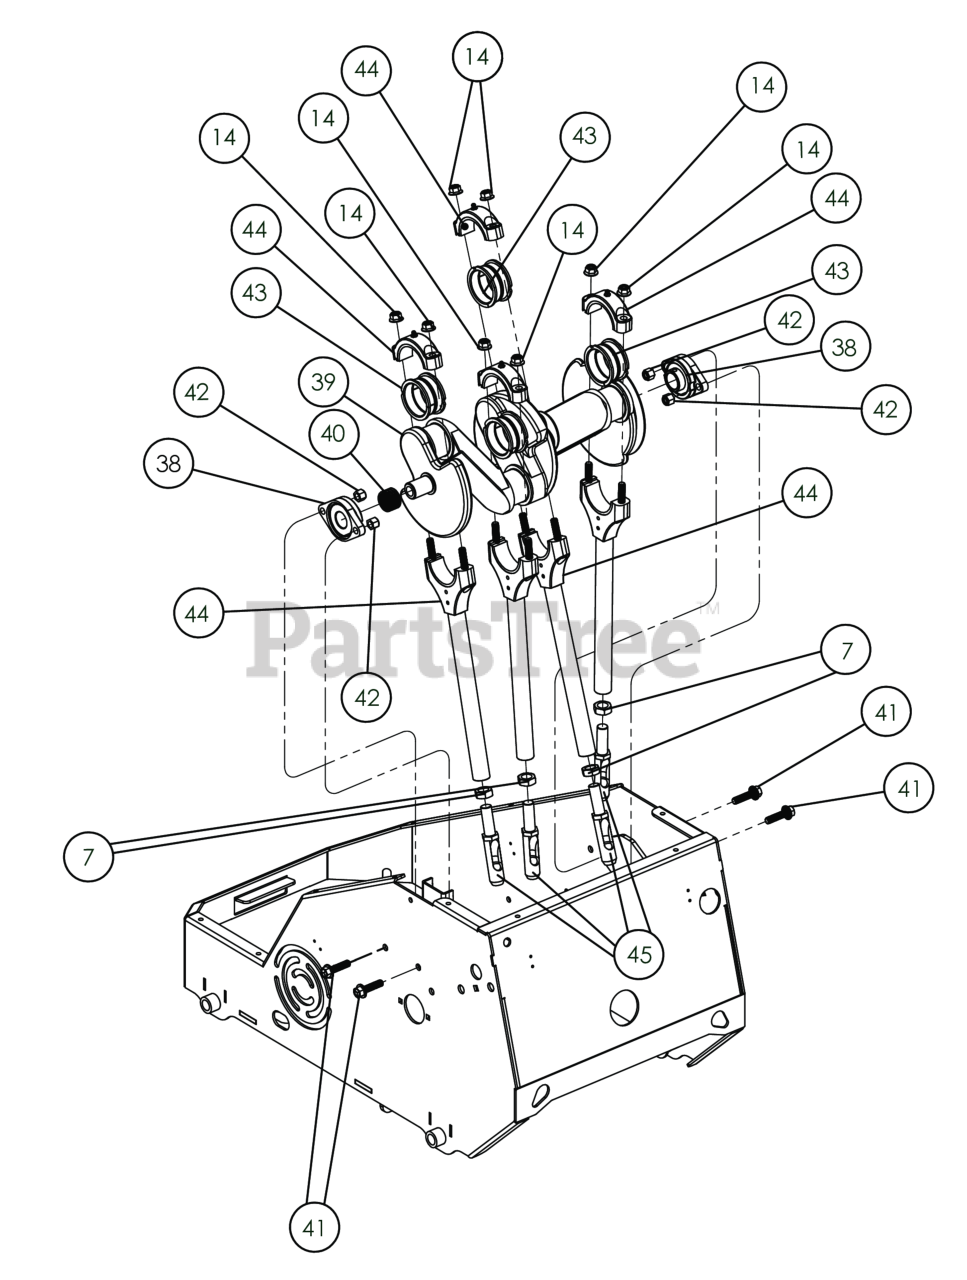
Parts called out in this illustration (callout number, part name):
7	NUT JAM, 5/8-11 ZP
14	NUT-HEX-NYLK, FLG .375"-16 ZP
38	CARTRIDGE BEARING
39	CRANKSHAFT (PL410)
40	SPRING, WAVE 1.000" X .700"
41	SCR-CAP, HSWH .375"-16 X 1.500" G5 ZP
42	NUT LOCK 3/8"-16 HEX
43	BEARING JOURNAL 2" DIA
44	ASM, TINE ROD AND CAP
45	TINE, PLUGR .625"-11 BLACK
